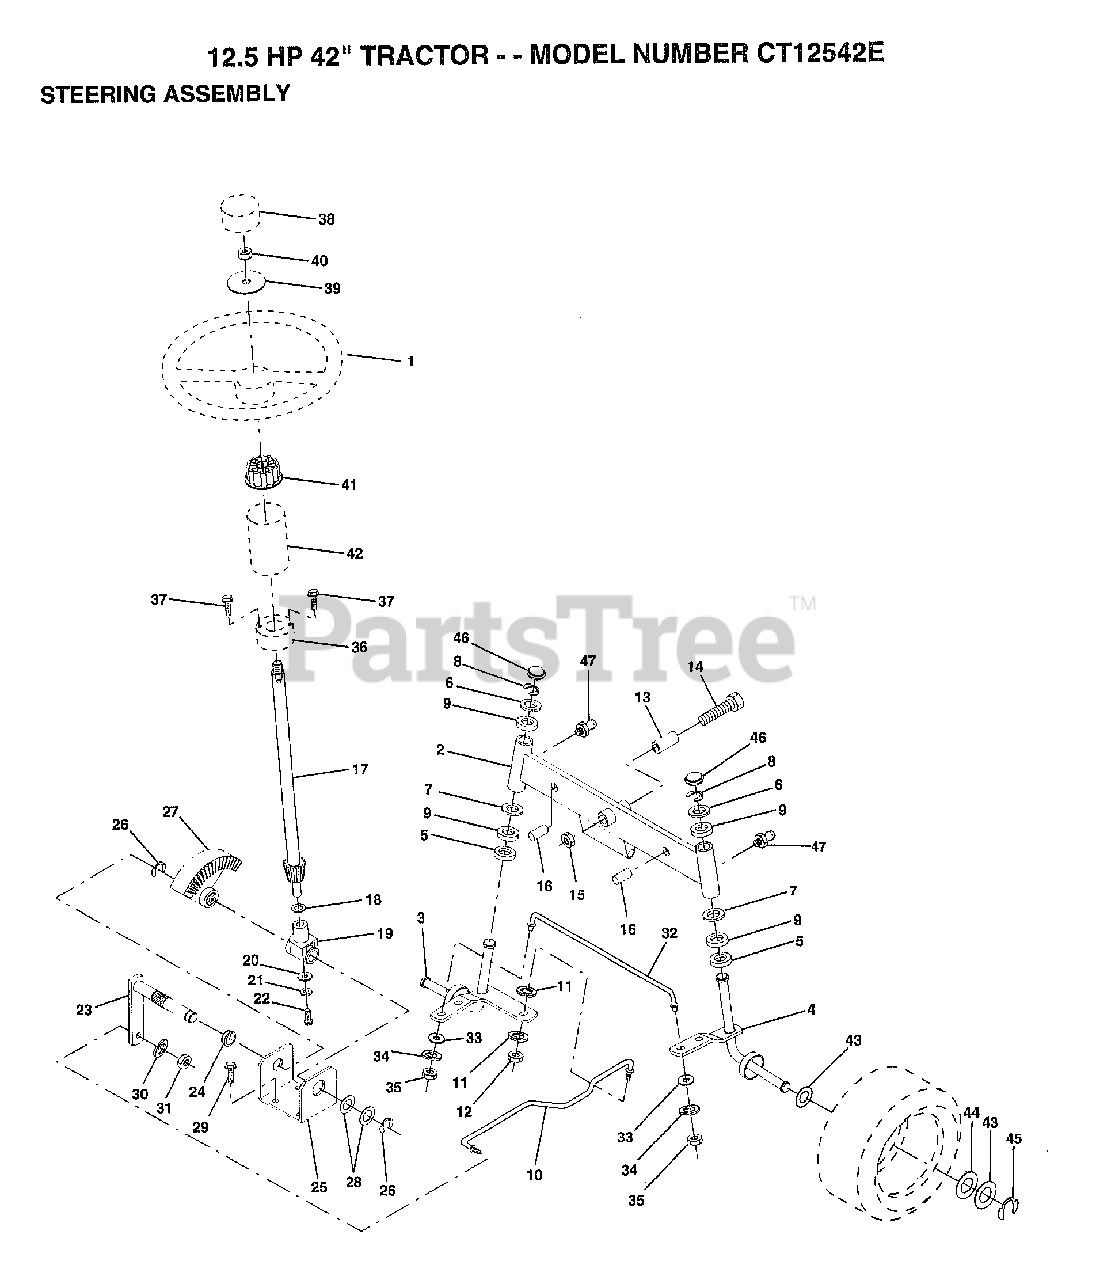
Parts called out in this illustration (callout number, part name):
1	WHEEL STR AYP BLK
2	AXLE ASM FRONT
3	SPINDLE LH
4	SPINDLE RH
5	WASHER .T
6	WASHER
7	WASHER
8	RING
9	COL. SRTG. BEAR.
11	LOCKWASHER
13	BEARING
14	BOLT HEX 5/8-11
15	"NUT-LOC,FLANGE LT"
16	AXLE PIN
17	SHAFT ASM
18	THRUST WASHER
19	SUPPORT.SHAFT
21	LOCKWASHER
22	"SCREW,SPECIAL"
24	NYLINER T
25	"BRKT,STEERING"
26	RING
27	GEAR SECTOR
28	WASHER .T
29	SCREW
30	LOCKWASHER
32	ROD.TIE.19.75
33	WASHER M
34	LOCKWASHER
35	NUT.LOCK.5/16-24
38	CAP STEER AYP
39	WASHER T
40	GRIPCO NUT
41	ADAPTER-WHEEL LT
42	"TUBE, STR SHAFT"
43	WASHER
44	WASHER
45	RING
46	CAP
47	ZERK M
